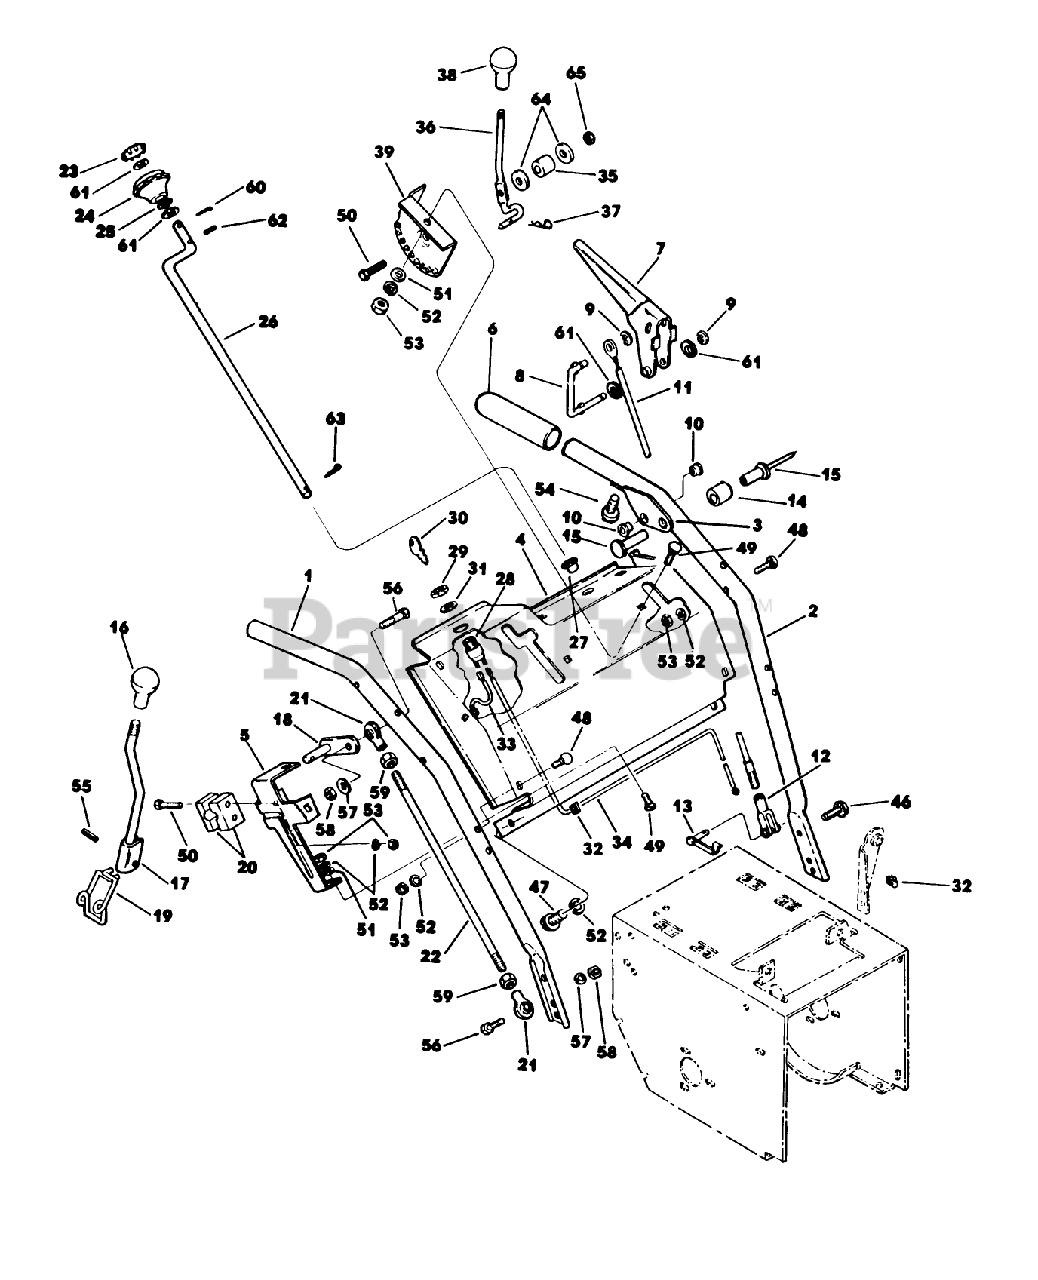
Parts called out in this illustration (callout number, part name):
1	HANDLE-R.H.
8	ROD CONTROL
11	CABLE ASM
12	YOKE-ADJUSTABLE
13	SPRING CLEVIS PIN
20	SHIFT LEVER BLOCK
23	PLUG BUTTON-KNOB
35	SPACER - RUBBER
37	PIN-HAIR
59	NUT-HEX
63	PIN-COTTER
65	NUT-LOCK, CONE
